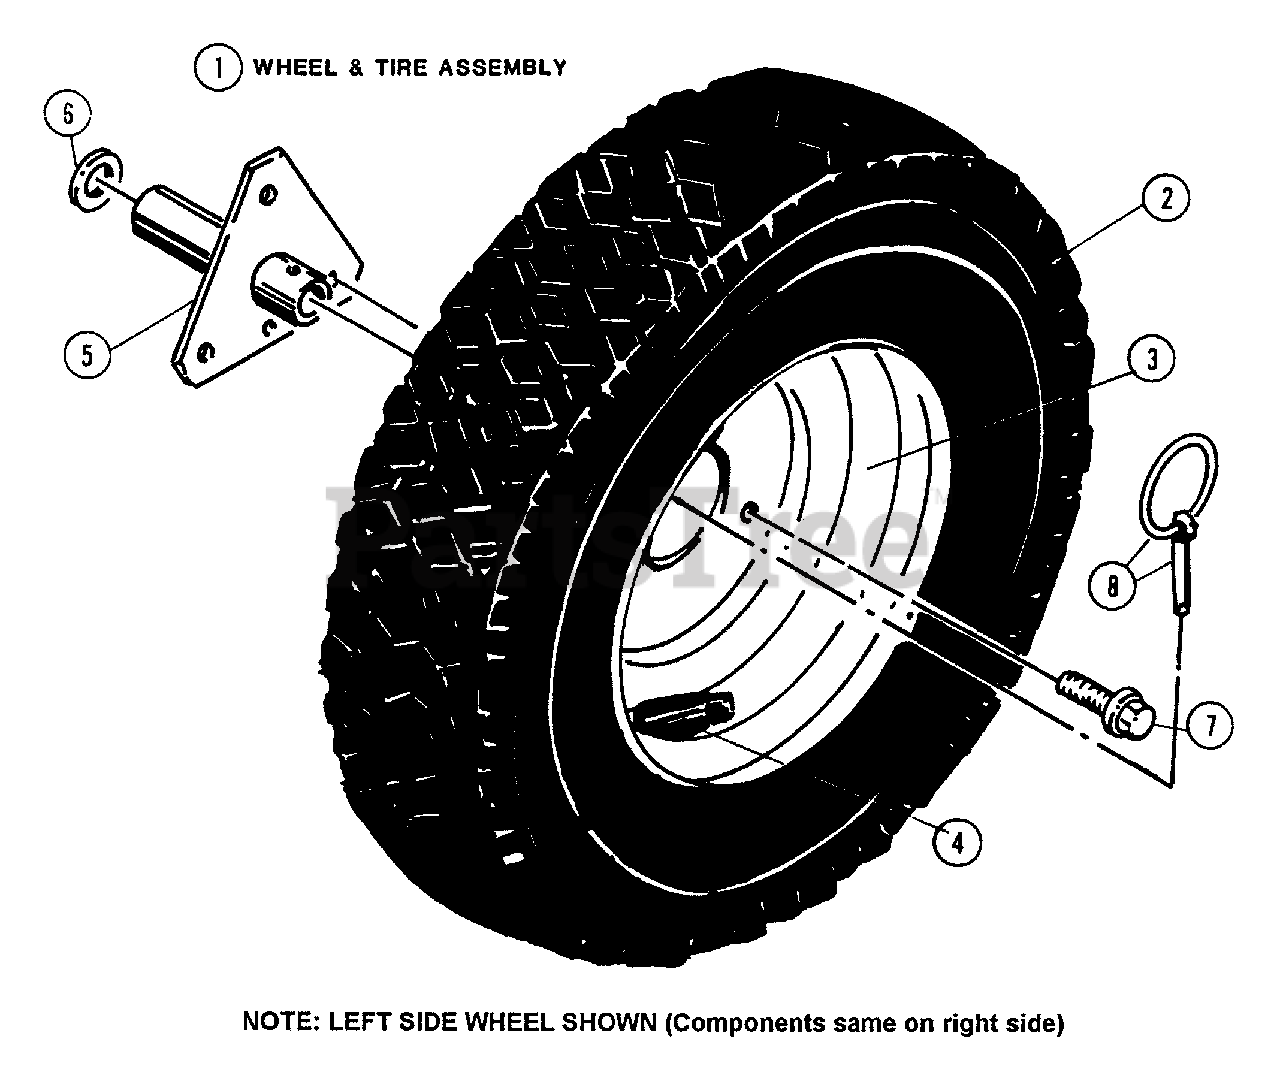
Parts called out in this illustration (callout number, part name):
1	WHEEL & TIRE ASSEMBLY- 23" & 26" Units
1	WHEEL & TIRE ASSEMBLY- 30" Units
2	TIRE, 16 x 4.80 - 8 (23" & 26" Units)
2	TIRE, 16 x 6.50 x 8 (30" Units)
3	RIM (23" & 26" Units)
3	RIM (30" Units)
4	VALVE, Air (Snap-in)
5	HUB, Wheel (Used on right & left side)
6	WASHER, 3/4" Flat
7	BOLT, 1/2-20 x 3/4" Hex Head Cap, Grade 2
8	RETAINER (Klick-pin)
